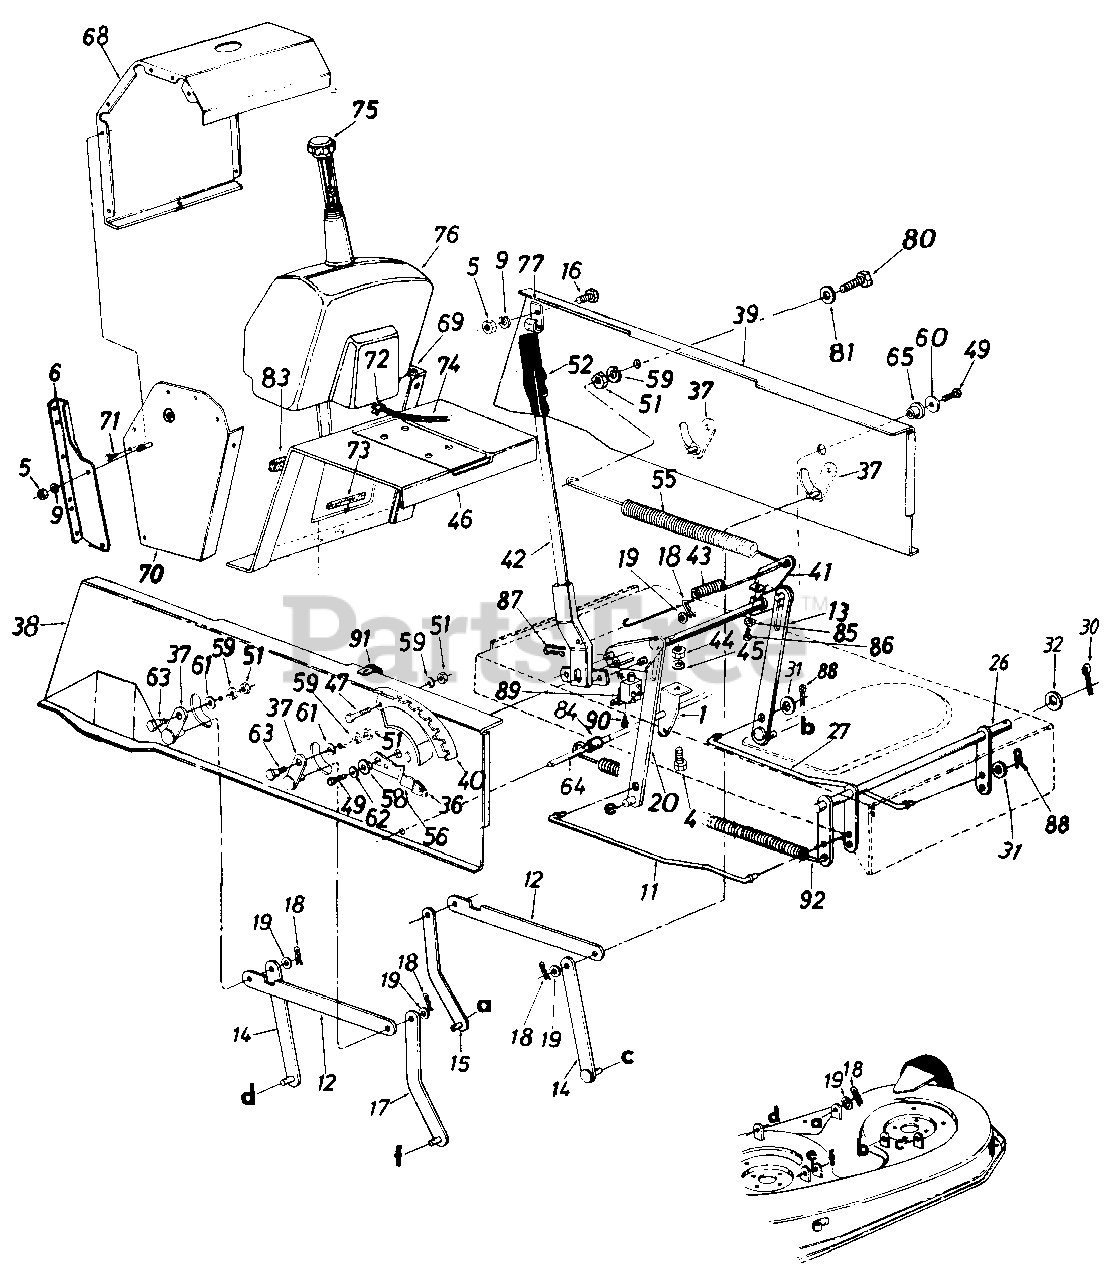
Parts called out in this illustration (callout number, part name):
1	Spring Hanger Bracket
4	Hex Bolt 1/4-20 x .62" Lg.
5	Hex Nut 5/16-18 Thd.
6	Mounting Bracket R.H.
9	L-Wash. 5/16" I.D.
11	Stabilizer Rod
12	Connecting Rod 3/16 x 1 x 12.5
13	Deck Lift Link Ass'y.
14	Deck Hanger Link Ass'y.
17	Deck Hanger Link Ass'y.
18	Inter. Cotter Pin 1/2" Dia.
19	Fl-Wash. .531 I.D. x .93" O.D.
20	Deck Lift Link Ass'y.
26	Stabilizer Shaft Ass'y.
27	Stabilizer Rod
30	Cotter Pin 1/8" Dia. x 1.25" Lg.
31	Fl-Wash. .385" I.D. x .620" O.D.
32	Fl-Wash. .635" I.D. x 1.12" O.D.
36	Knob Height Adj.
37	Pivot Link Ass'y.
38	Side Panel Upper Frame R.H.
39	Side Panel Upper Frame L.H.
40	Index Brkt.
41	Lift Shaft Ass'y.
42	Lift Handle Brkt. Ass'y.
43	Ext. Spring
44	Hex Nut 1/4-20 Thd.
45	L-Wash. 1/4" I.D.
46	Hitch Plate
47	Hex Bolt 5/16-18 x .75" Lg.
49	Hex Wash. TT-Tap Scr. 5/16-18 x .62" Lg.
51	Hex Nut 5/16-18 Thd.
52	Grip
55	Ext. Spring .99" Dia. x 11.00" Lg.
56	Deck Lift Down Stop
58	Flange Brg. .630" I.D.
59	L-Wash. 5/16" I.D.
60	Fl-Wash. .344" I.D. x 1.125" O.D.
61	Fl-Wash. .344" I.D. x .62" O.D. x .063
62	Fl-Wash. .344" I.D. x 1.125" O.D.
63	Shld. Bolt .437" Dia. x .180
64	Running Board Rod
65	Flange Brg. .632" I.D.
68	Gas Tank Housing Main Panel
71	Truss. Mach. B-Tap Scr. #10 x .50" Lg.
72	Hose Clamp .406" Dia.
73	Trim Strip 5" Lg.
74	Gas Line 44" Lg.
75	Gas Tank Cap
76	Gas Tank
77	Hose Clamp
80	Hex Bolt 5/16-18 x 1.50" Lg.
81	Fl-Wash. .344" I.D. x .875" O.D.
83	Foam Strip 3/8" x 1-1/8" x 1-1/2" Lg.
84	Spacer .523" I.D. x .640" O.D. x 1.95" Lg.
85	Hex Jam Nut 5/16-18 (Grade 5)
86	Hex Wash. Hd. Tap Scr. 5/16-18 x 1" Lg.
87	Internal Cotter Pin 3/8" Dia.
88	Cotter Pin 3/32" Dia.
89	Safety Switch
90	Truss Mach. Scr. #10 x .5" Lg.
91	Clamp
92	Ext. Spring 13.25" Lg.
